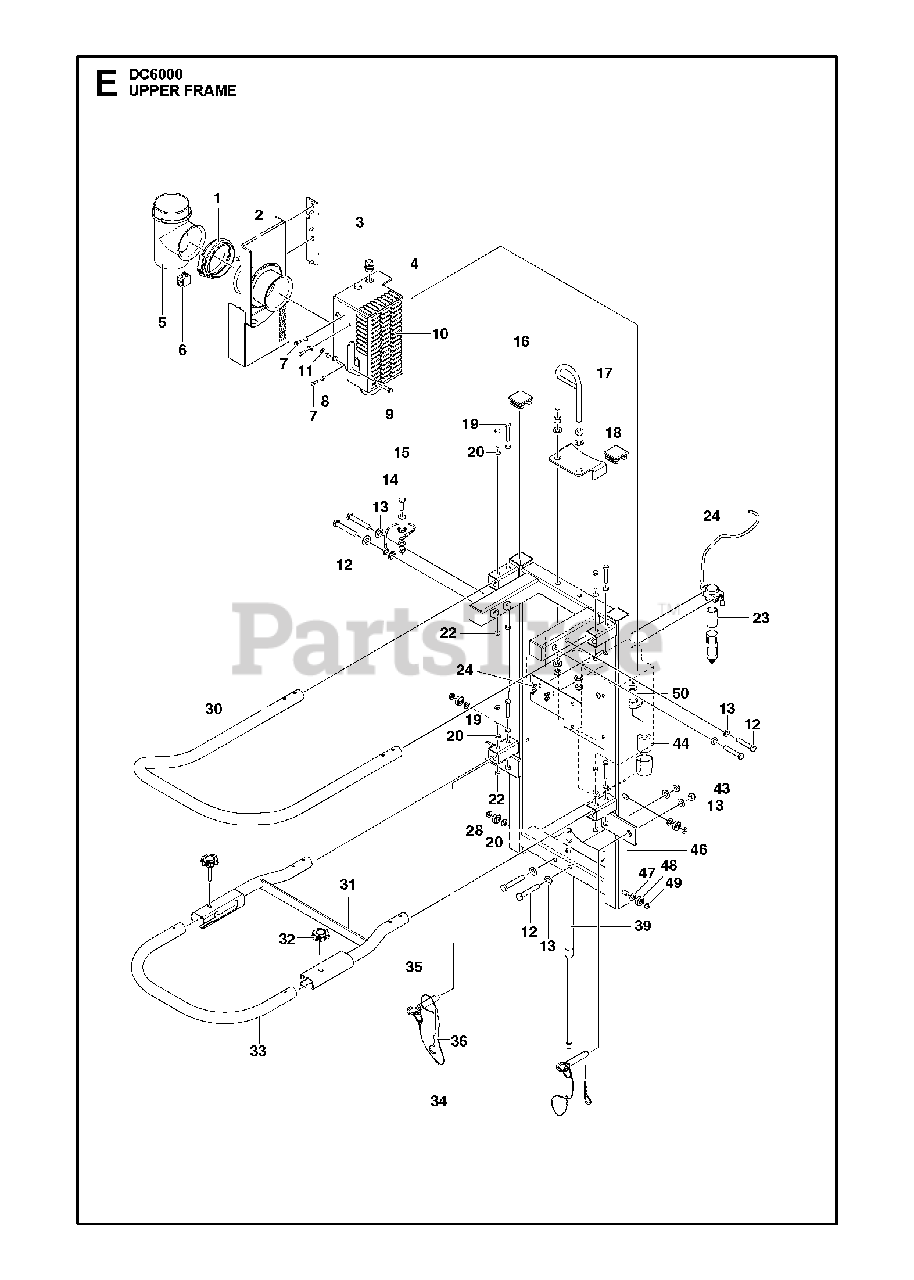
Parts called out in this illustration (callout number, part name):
11	HEXAGON LOCKING NUT
13	WASHER
20	WASHER
22	HEXAGON LOCKING NUT
28	HEXAGON NUT
36	SPRING COTTER
47	WASHER
